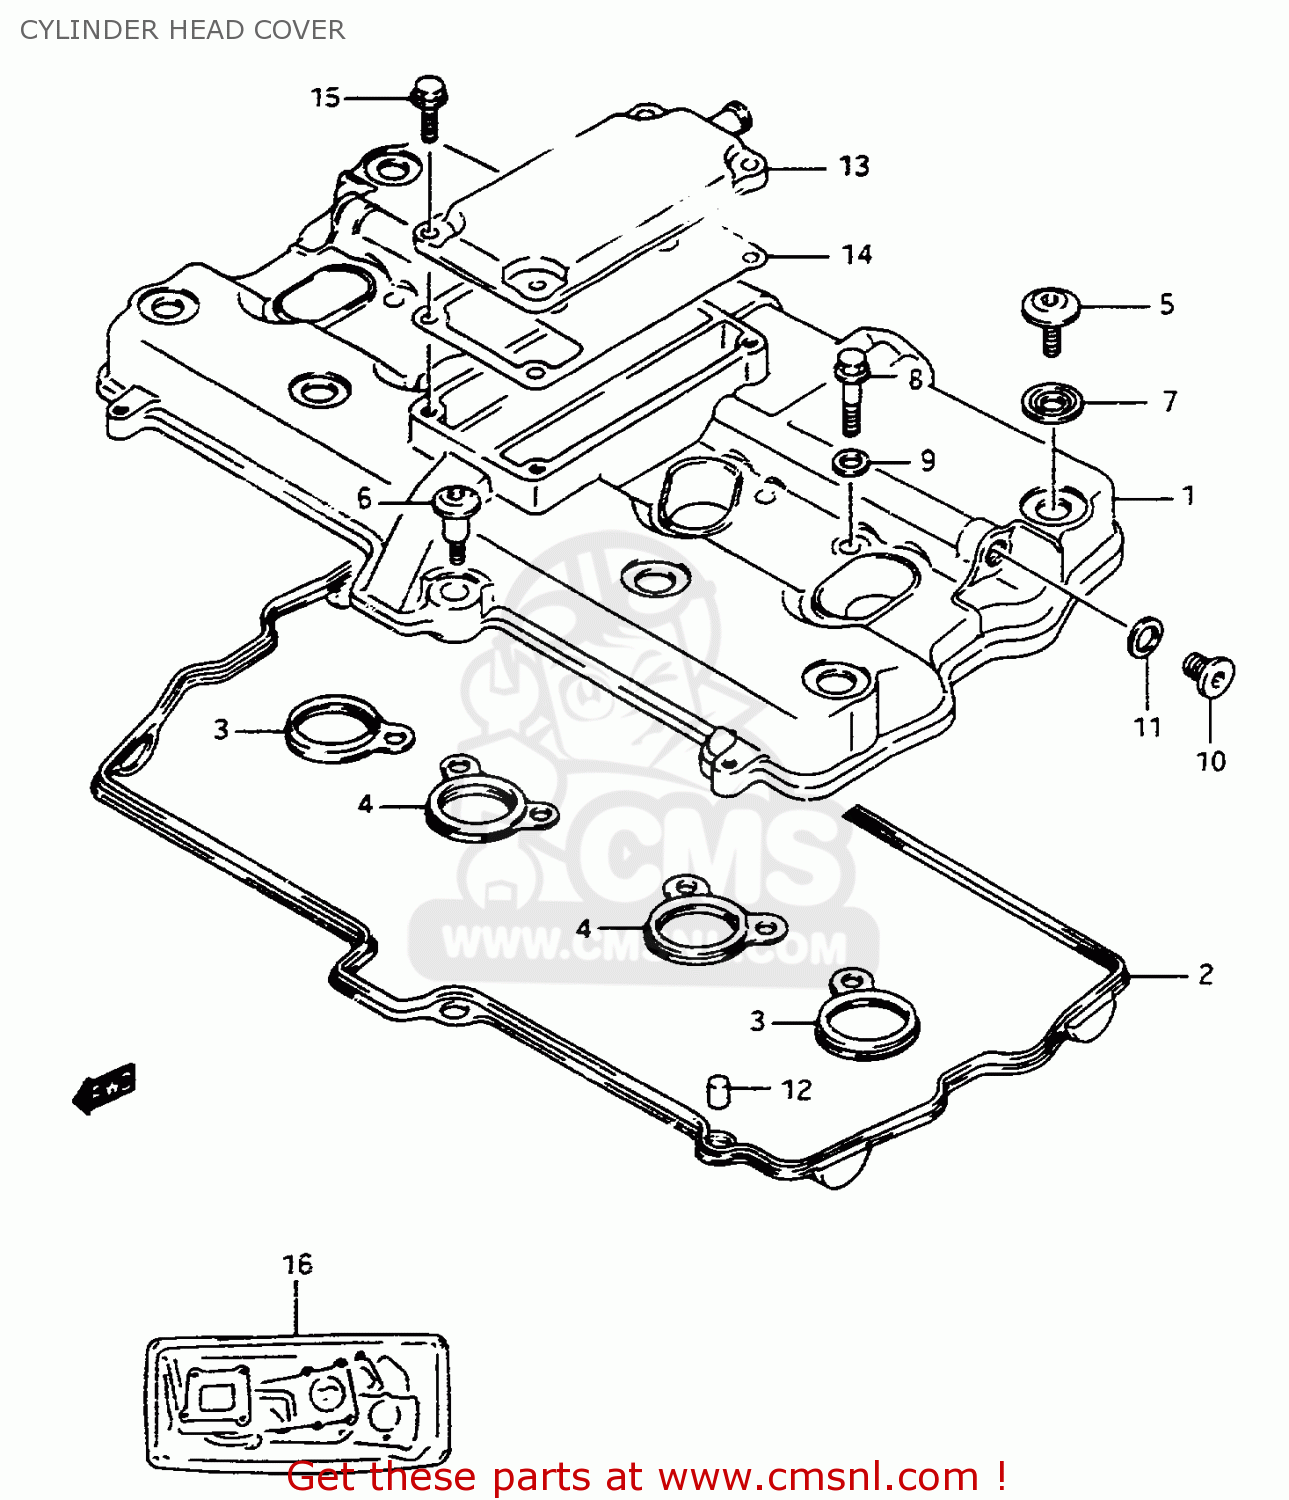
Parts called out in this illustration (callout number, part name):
1	COVER,CYLINDER HEAD
2	GASKET,CYLINDER HEAD COVER (NAS)
3	GASKET,HEAD COVER NO.2 (NAS)
4	GASKET,HEAD COVER NO.3 (NAS)
5	BOLT(7X17.5)
6	BOLT(7X31)
7	WASHER(10.6X25.5X2.3)
8	BOLT,UNION 8X35
9	GASKET 8.2X14X1 (NAS)
10	PLUG(L:12)
11	GASKET(12.1X16.2X3.7) (NAS)
12	PIN
13	COVER,BREATHER
14	GASKET,BREATHER COVER (NAS)
15	BOLT
16	GASKET SET (NAS)
